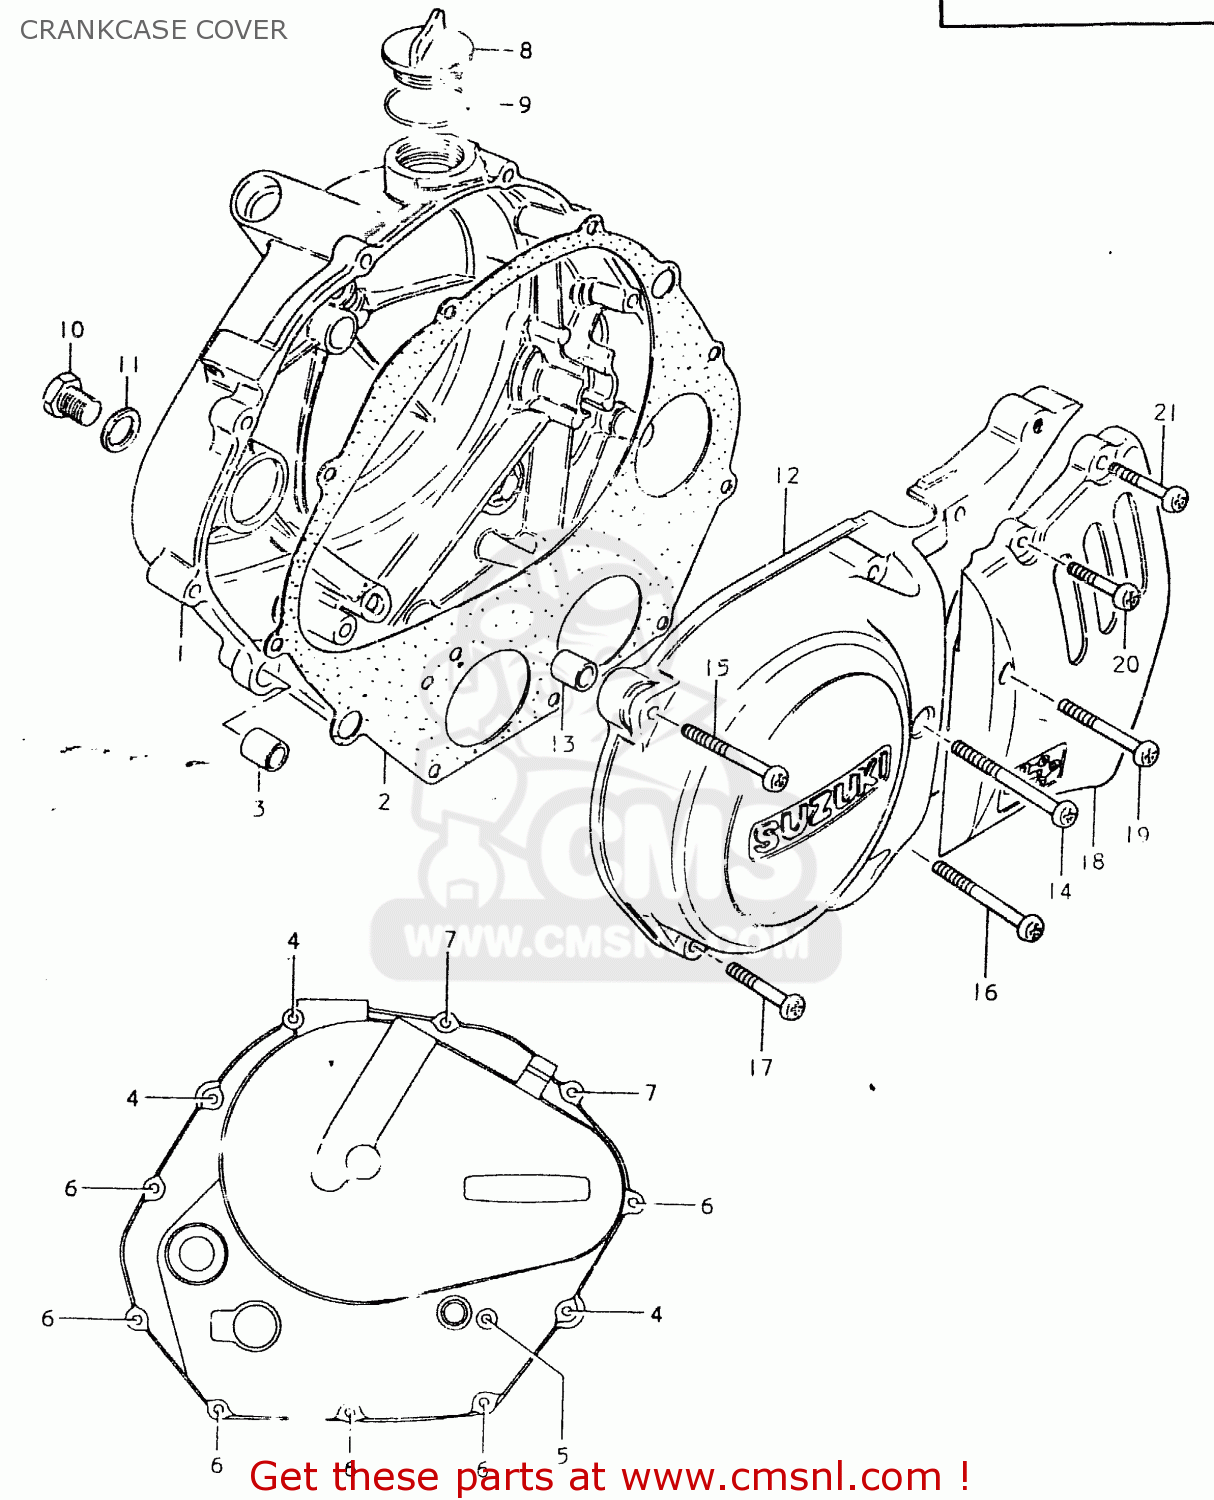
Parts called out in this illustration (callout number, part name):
1	COVER,CLUTCH
2	GASKET,CLUTCH COVER (MCA)
3	PIN
4	SCREW
5	SCREW
6	SCREW (6X35)
7	SCREW
8	CAP
9	O RING(D:2.2,ID:32)
10	PLUG (14X12)
11	GASKET(14X19.2X2) (NAS)
12	COVER
13	PIN
14	SCREW 6X60
15	SCREW
16	SCREW (6X45)
17	SCREW (6X35)
18	COVER,SPROCKET
19	SCREW
20	SCREW
21	SCREW
